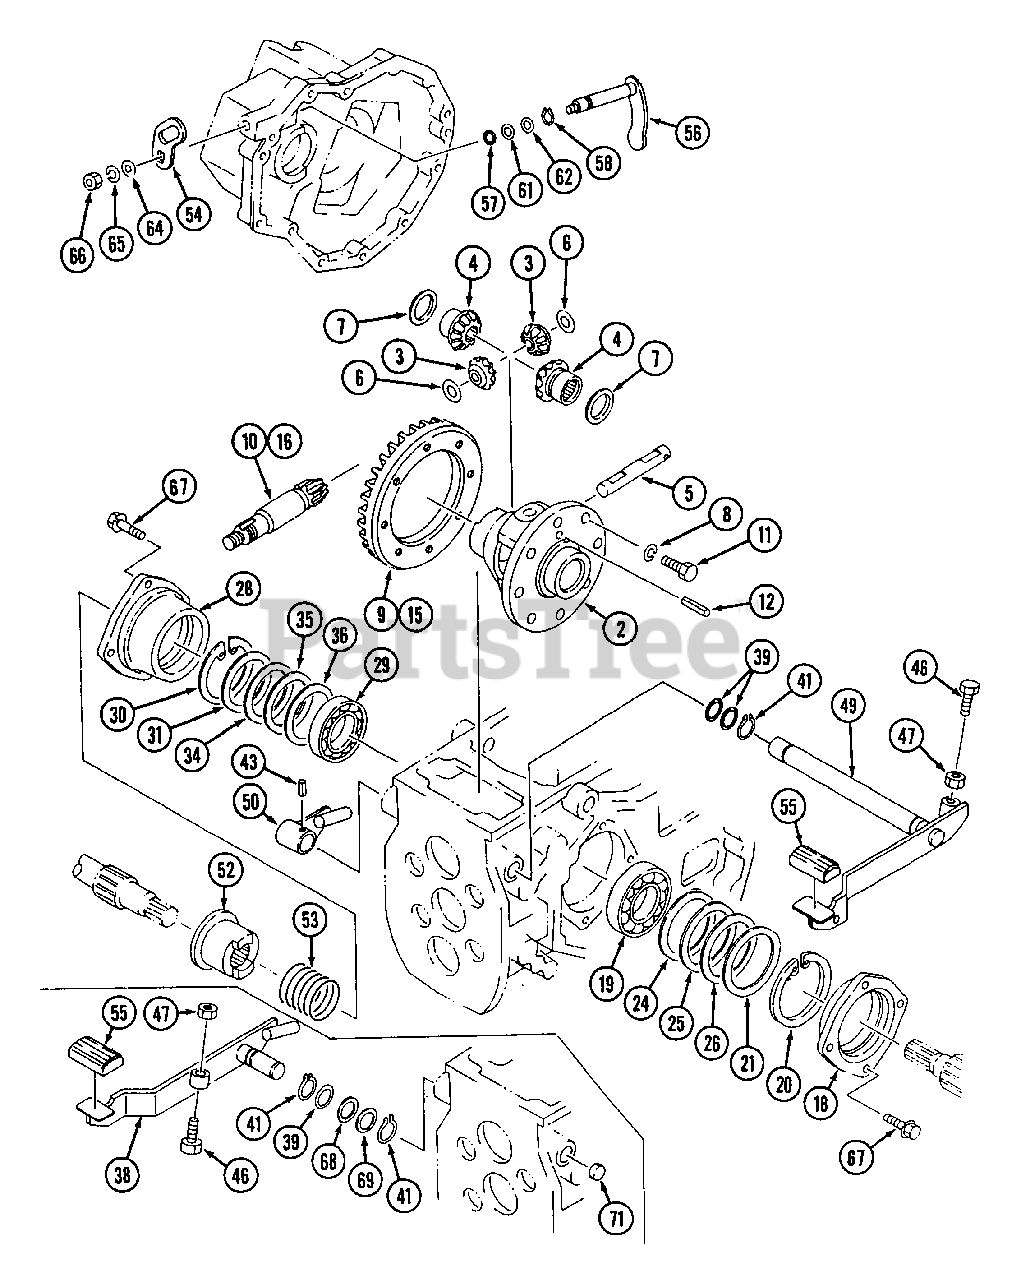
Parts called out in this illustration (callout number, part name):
5	Shaft, Pinion
6	Washer, Thrust
7	Washer, Thrust
9	Gear, Ring
10	Shaft, Pinion
15	Gear, Ring
16	Shaft, Pinion
38	Pedal Diff. Lock
43	Pin, Spring
49	Pedal, Diff. Lock
50	Arm, Diff. Lock
